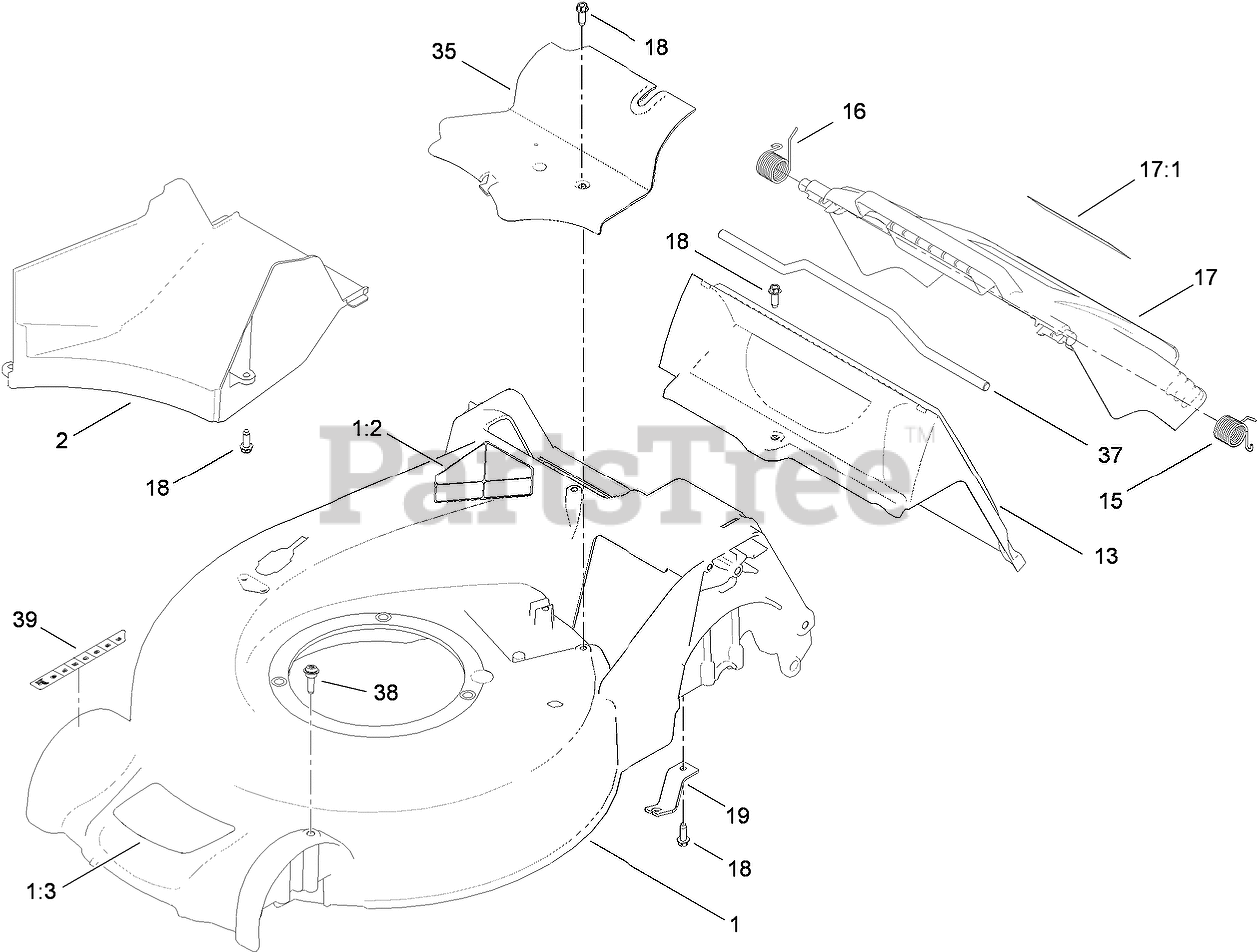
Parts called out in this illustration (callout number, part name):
1	HOUSING ASM
1:2	DECAL-DANGER
1:3	DECAL-HOUSING
2	RAMP-DISCHARGE
15	SPRING-TORSION
16	SPRING-TORSION
17	REAR DOOR ASM
17:1	DECAL-WARNING
18	SCREW-HWHTF
19	BRACKET-CABLE, TRACTION
35	COVER-BELT
37	ROD-DEFLECTOR
38	SCREW-SHOULDER, BHTF
39	DECAL-HOC
